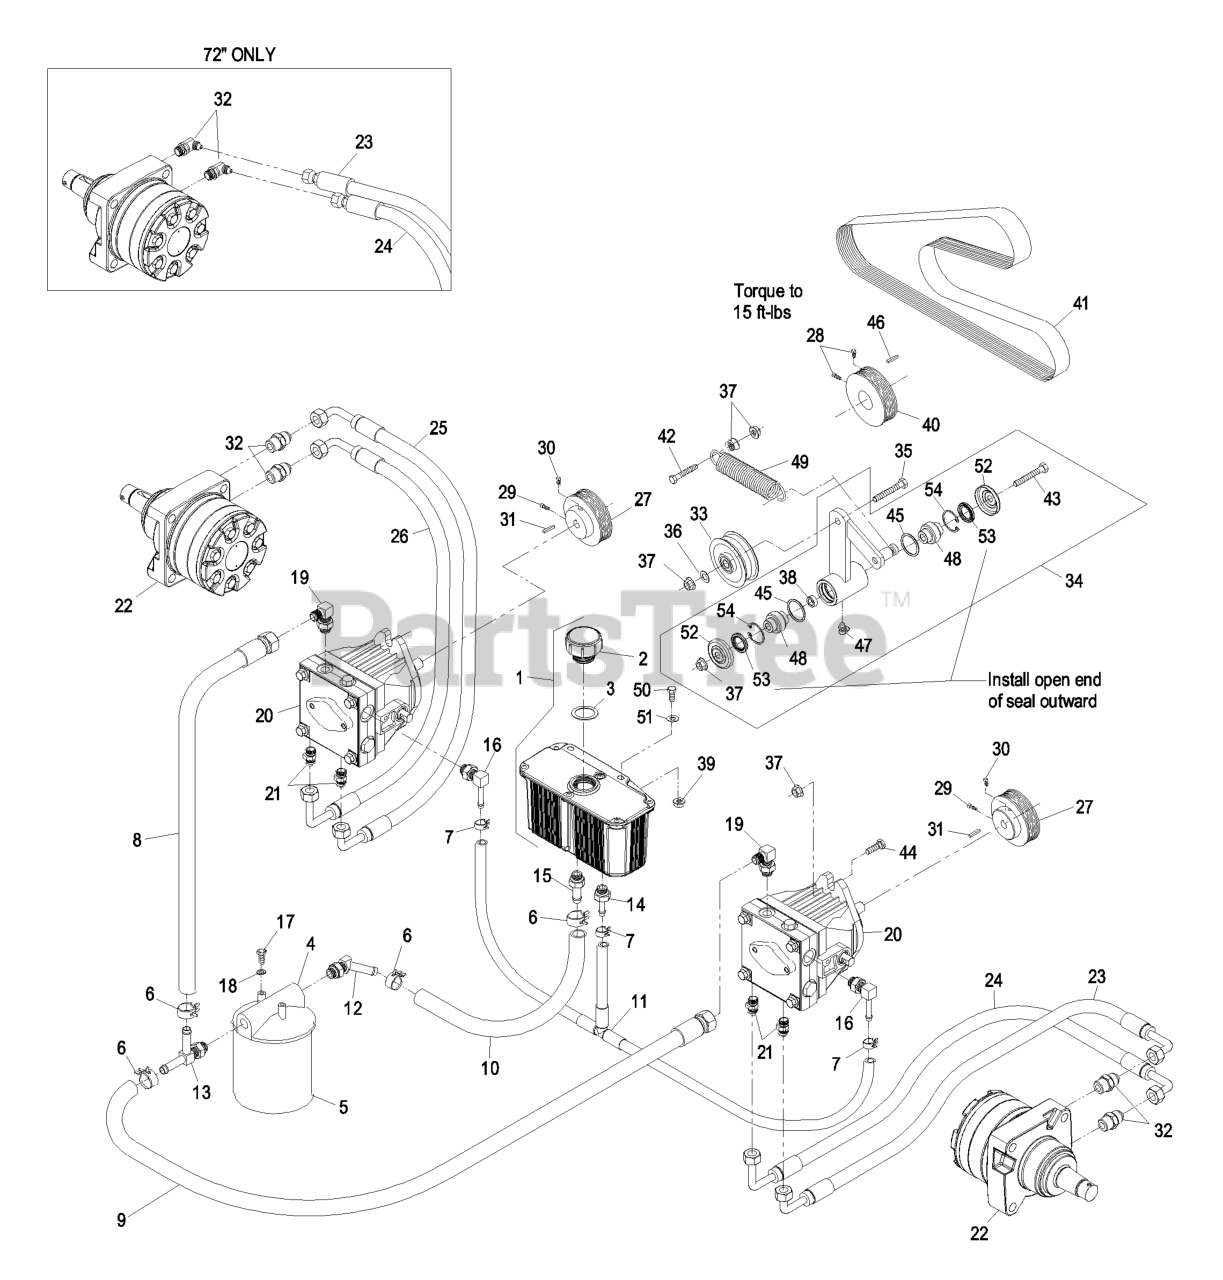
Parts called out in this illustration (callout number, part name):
1	HYD RESERVOIR ASM
2	Cap-Reservoir, HYD
3	GASKET-CAP
4	HEAD-FILTER
6	CLAMP-HOSE
7	CLAMP-HOSE
8	HYD HOSE ASM
9	HYD HOSE ASM
10	HOSE-HYD
11	HYD HOSE ASM
12	FITTING-BARBED, 45 DEG
13	ADAPTER-RUN, TEE
14	ADAPTER-STRAIGHT
15	ADAPTER-STRAIGHT
16	ELBOW-90 DEG
17	SCREW-HH
18	WASHER-LOCK
19	FITTING-ELBOW, 90 DEG
21	FITTING-STRAIGHT
23	HYD HOSE ASM
24	HYD HOSE ASM
25	HYD HOSE ASM
26	HYD HOSE ASM
27	SHEAVE
28	SCREW-SET
29	SCREW-SET
30	SCREW-SET
31	KEY-SQUARE
32	FITTING-STRAIGHT
33	SHEAVE-IDLER
34	KIT,PUMP IDLER LZ
35	SCREW-HH
36	WASHER-FLAT
37	NUT-HHF, WHIZ
41	BELT, POLY-V K
42	SCREW-HH
43	SCREW-HH
44	SCREW-HH
46	KEY-SQUARE
47	FITTING-GREASE, 90 DEG
48	BEARING-SPHERICAL
50	SCREW-HH
51	WASHER-FLAT
52	GUARD-TOP
53	SEAL-LIP, SINGLE
54	RING-SNAP
